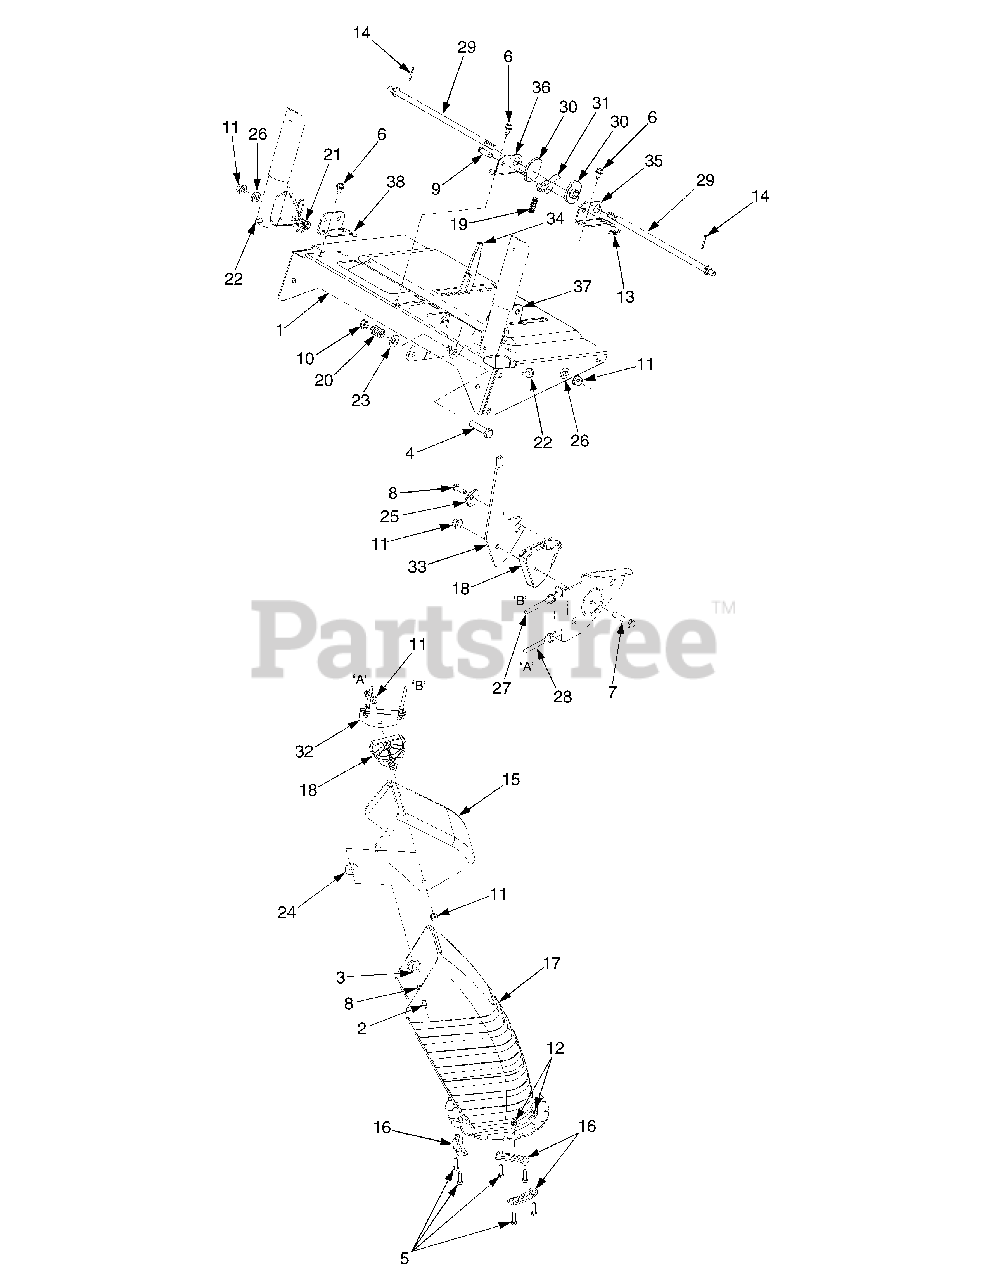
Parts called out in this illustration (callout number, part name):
2	Screw, Carriage, 5/16-18 x 1.0
3	Screw, Carriage, 5/16-18 x 1.75
4	Screw, Hex Cap, 3/8-24 x 1.5 GR5
5	Screw, Hex Cap, 1/4-20 x 1.0 GR5
6	Screw, Hx Wash Hd Tapp 1/4-20 x .5
7	Screw, Hex Cap, 5/16-18 x 1.5 GR5
8	Screw, Hx Wash Hd Tapp 1/4-15 x .75
9	Pin, Clevis, .312 x 1.0
10	Nut, Insert Jam Lk, 3/8-24 GR5
11	Nut, Hx Insert Flnge Lk, 5/16-18 GrF
12	Nut, Hx Insert Flnge Lk, 1/4-20 GrF
13	Pin, Internal Cotter
14	Pin, Cotter, 3/32 x .75
15	Chute, Upper, 6.0
16	Flange Keeper, Chute
17	Chute, Lower
18	Cable Guide, Chute Tilt
19	Spring, Compression
20	Spring, Compression
21	Spring, Torsion
22	Bumper, Rubber
23	Washer, Belleville, .375 x .87 x .063
24	Washer, Flat, .344 x 1.125 x .12
25	Washer, Special, .286 x 1.25 x .06
26	Washer, Flat, .35 Sq x .72 x .134
27	Cable, Chute Control, 66"
28	Cable, Chute Control w/Clip, 66"
30	Cam, Handle Lock
31	Pawl, Handle Lock
